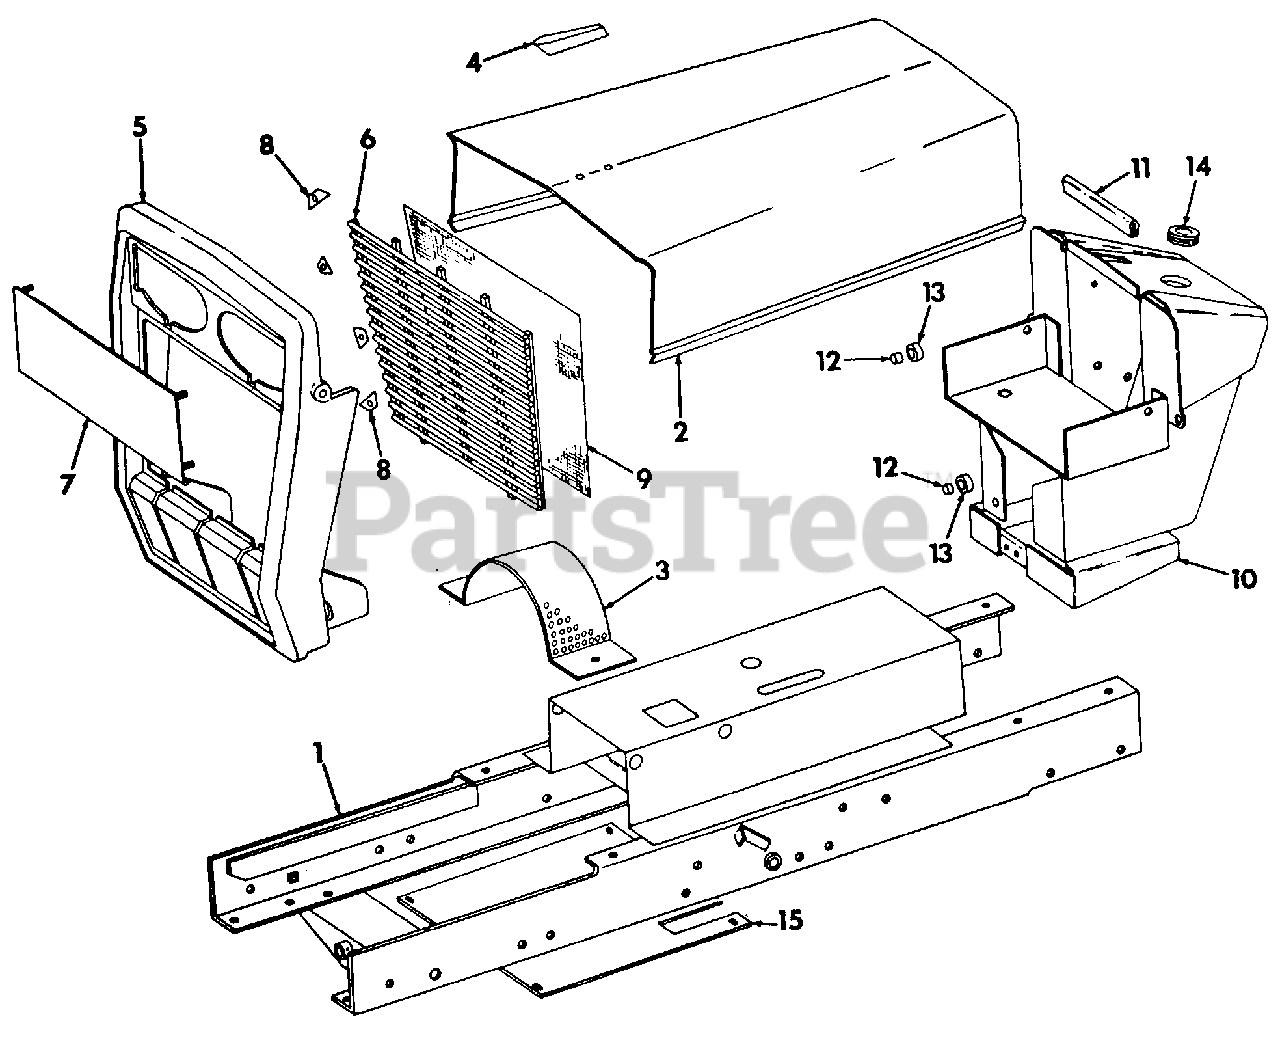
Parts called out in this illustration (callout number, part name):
1	Frame Assy
2	Hood Assy
3	Shield, Clutch
4	Product Graphic, Hood Ornament
5	Housing, Grille
6	Grille
7	Strip Assy, Grille Panel
8	Strip, Grille Panel Clamp
9	Screen, Grille
10	Pedestal Assy
11	Bumper, Hood
12	Spacer, Hood Roller Lock
13	Roller, Hood Lock (Rubber)
14	Grommet, Instrument Panel
15	Sheet, Bottom Clutch Shield
